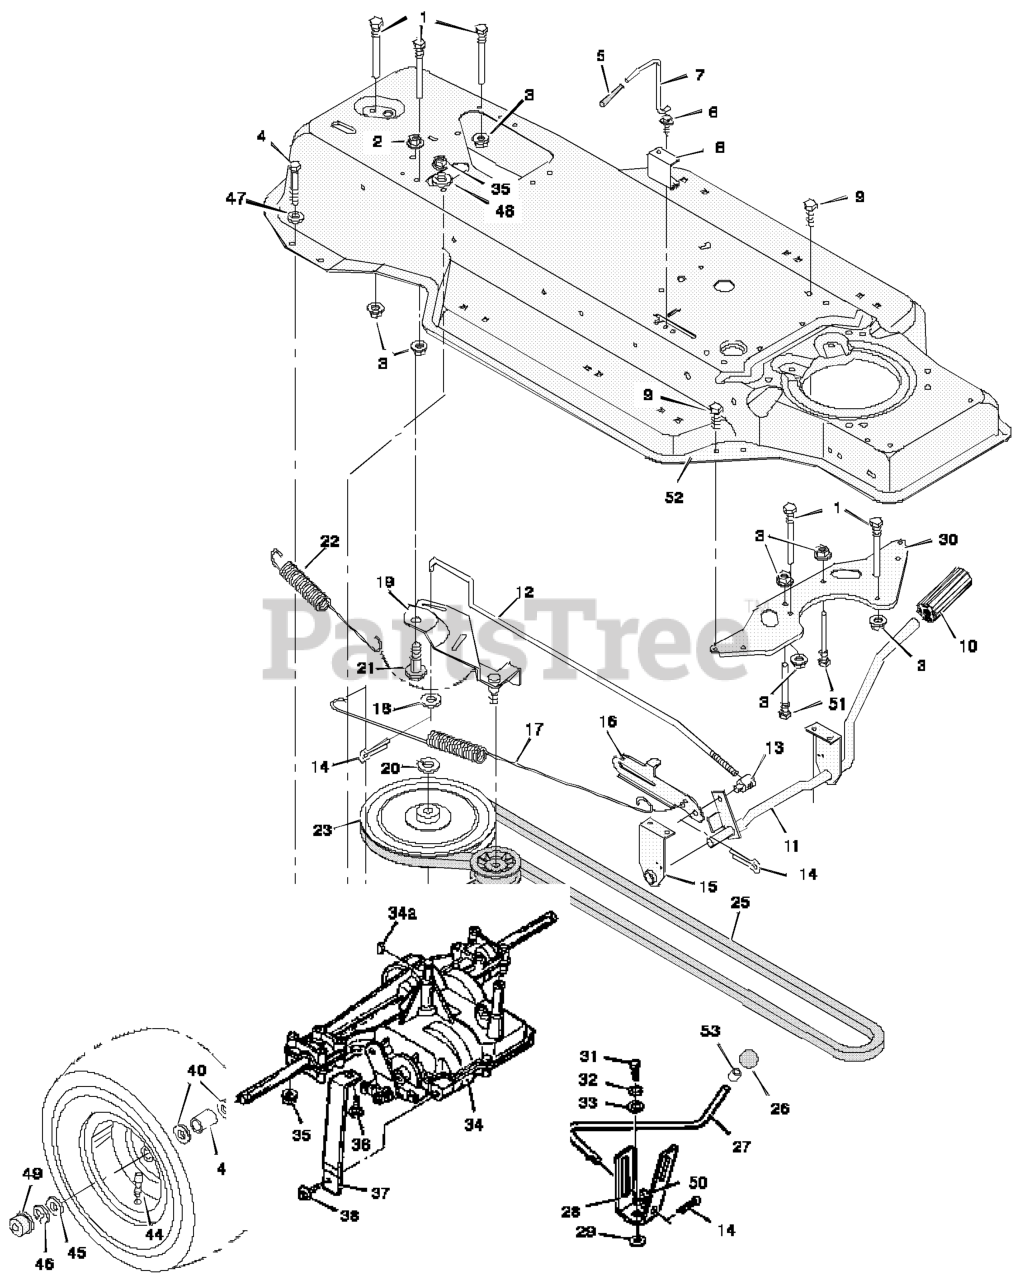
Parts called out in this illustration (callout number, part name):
1	Guide, Belt
2	Locknut, Flange
3	Nut, Flange
4	Bolt, Hex
7	Rod, Control
8	Guide, Bracket
10	Clutch and Brake Pedal
11	Lever Assembly
12	Rod, Clutch
13	Nut, Adjustable
14	Pin, Cotter
15	Bracket, Support
16	Latch, Park Brake
17	Spring, Brake Extension
18	Washer
19	Bracket Assembly, Idler
20	Ring, Retainer
21	Bolt, Shoulder
22	Spring, Drive Extension
23	Pulley, Motion Drive
24	Pulley, Backside Idler
25	Belt, Motion Drive
26	Knob, Shift Lever
27	Lever, Shift
28	Yoke, Shift
30	Plate, Belt Guide
31	Bolt Hex
32	Lockwasher
34	Transaxle, Peerless **
34A	Woodruff Key No. 9
35	Nut, Flange
36	Bolt, Carriage
37	Support, Transaxle
39	Key, Square
41	Spacer, Transaxle
43	Wheel & Tire Assembly
44	Stern, Valve
47	Washer
49	Hub Cap
50	Washer
51	Guide, Belt
52	Frame Assembly
53	Ring, Tolerance
